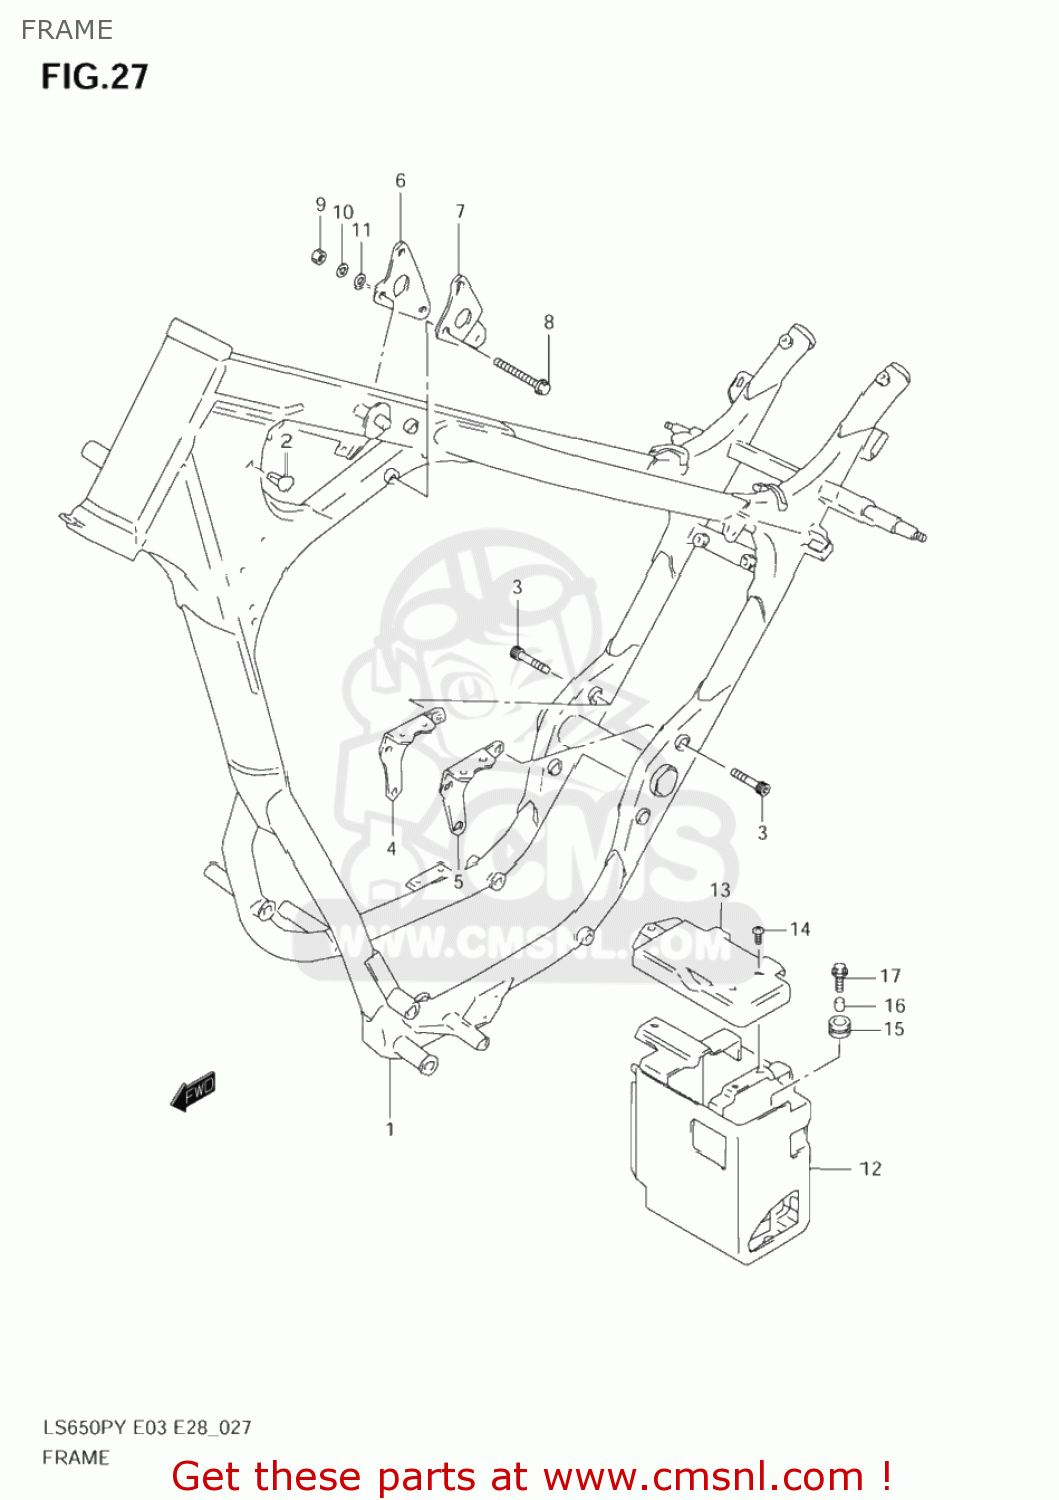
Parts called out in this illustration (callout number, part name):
1	FRAME(BLACK)
2	CLIP
3	BOLT(8X40)
4	PLATE,ENGINE MOUNT NO.4,R
5	PLATE,ENGINE MOUNT NO.4,L
6	PLATE,ENGINE MOUNT NO.5,R
7	PLATE,ENGINE MOUNT NO.5,L
8	BOLT(8X72)
9	NUT
10	LOCK WASHER
11	WASHER
12	HOLDER,BATTERY
13	COVER,BATTERY
14	SCREW
15	CUSHION
16	SPACER
17	BOLT
